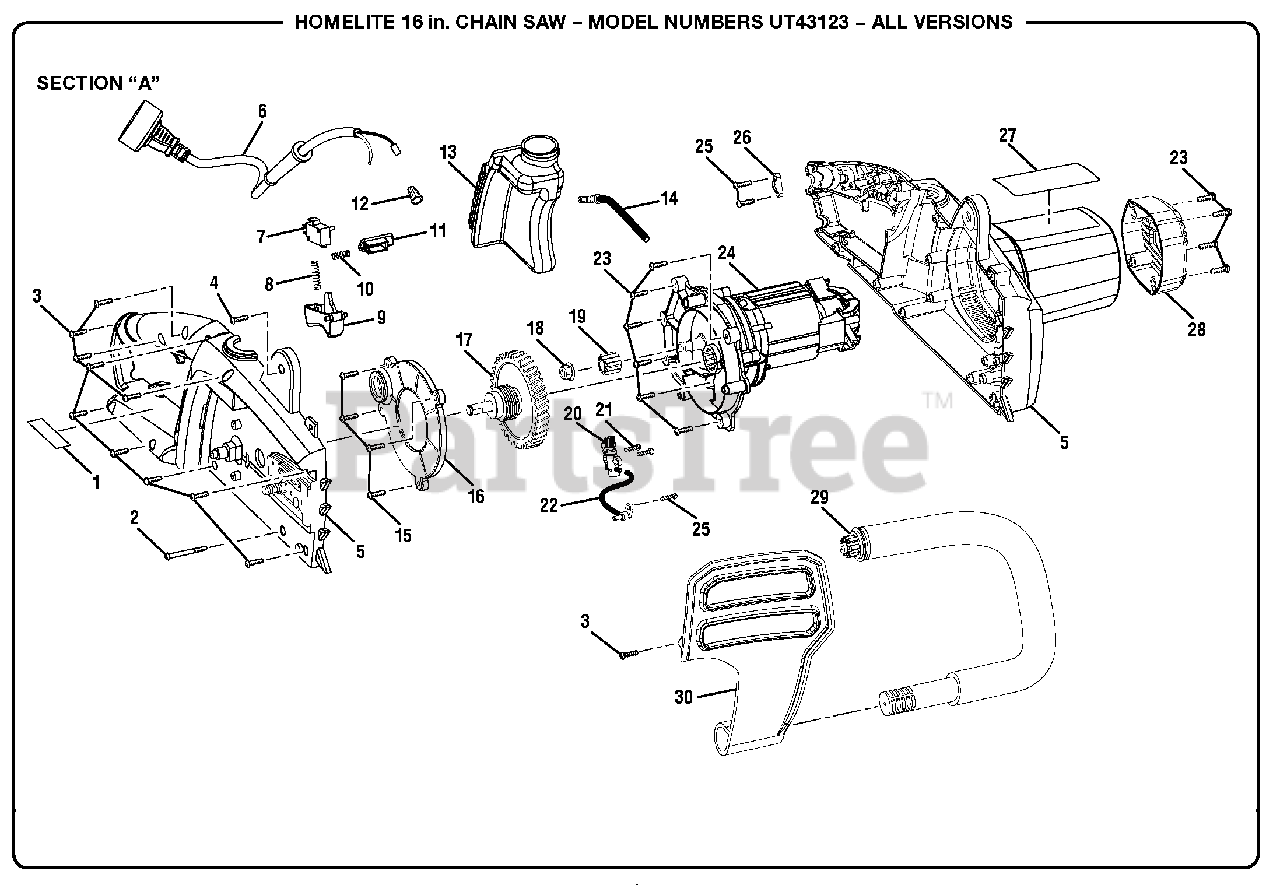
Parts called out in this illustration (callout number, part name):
1	Warning Icon Label
2	Screw (M5 x 35 mm)
3	Screw (M4 x 16 mm)
4	Screw (M4 x 20 mm)
5	Housing Assembly
6	Power Cord
8	Compression Spring (Trigger)
9	Switch Trigger
10	Compression Spring (Lock-Off)
11	Lock-Off Button
13	Oil Reservoir Assembly
14	Oil Outlet Tube
15	Screw (M4 x 12 mm)
16	Gear Cover
17	Gear Assembly
18	Flange Nut (M8)
21	Screw (M3 x 10 mm)
22	Oil Inlet Tube
23	Screw (M4 x 16 mm)
24	Motor Assembly
25	Screw (M4 x 10 mm)
26	Cord Clamp
27	Data Label
28	Motor End Cap
